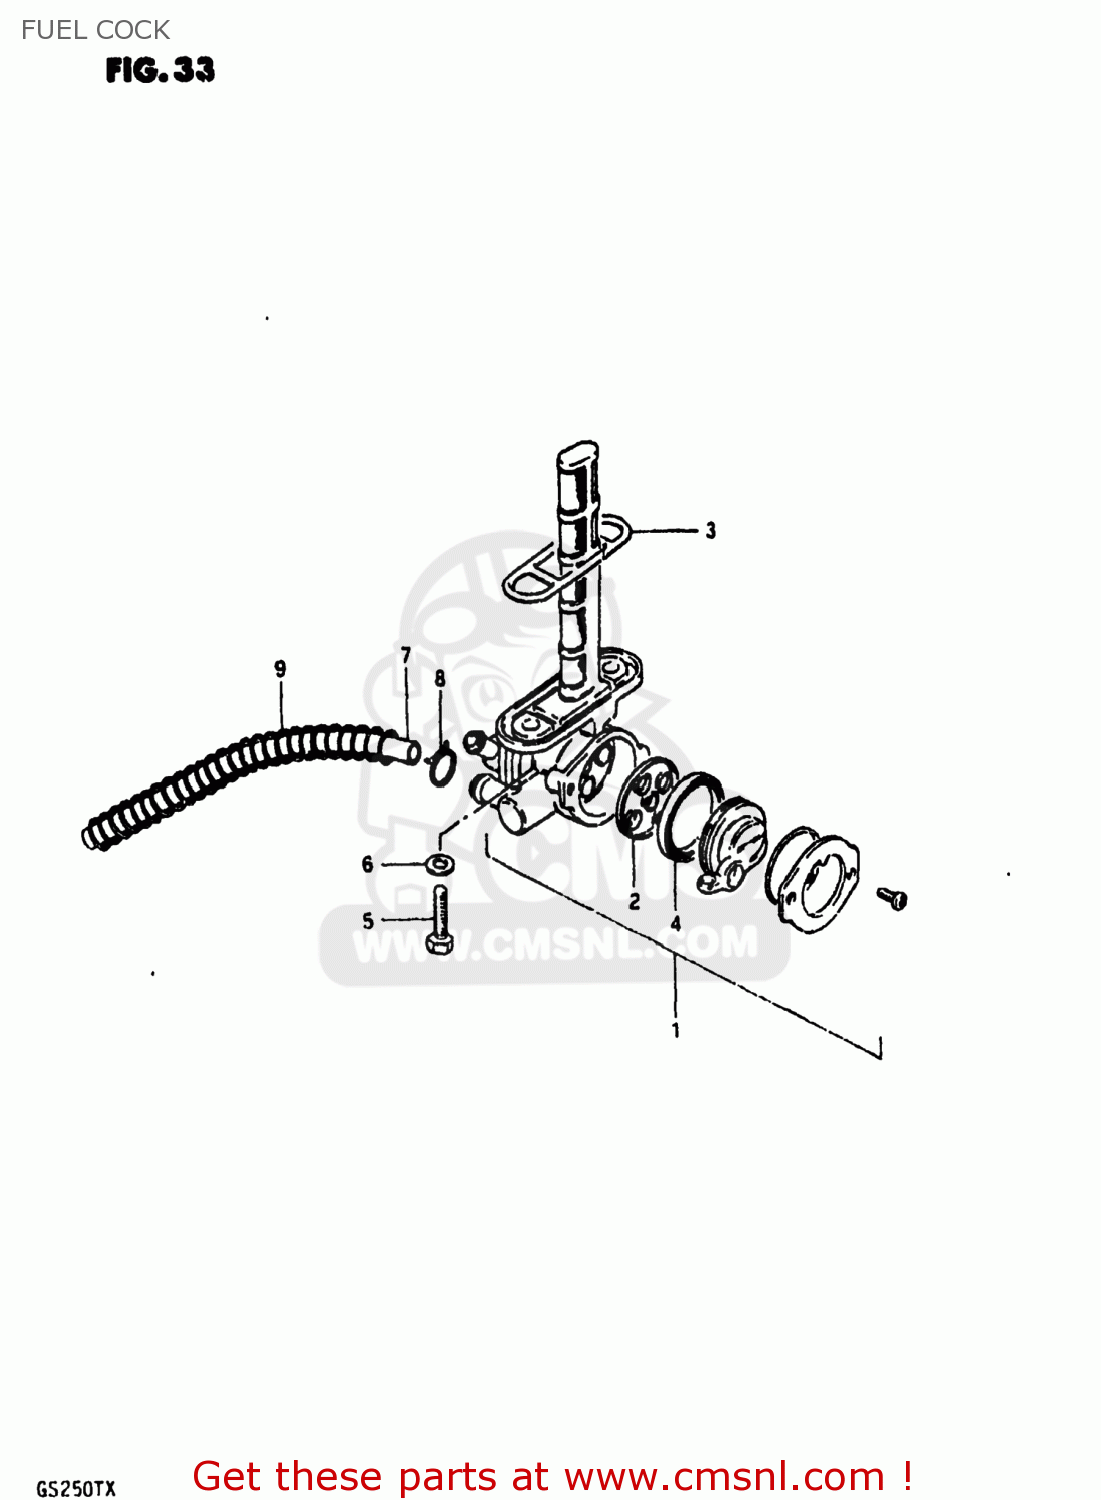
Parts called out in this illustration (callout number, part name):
1	COCK ASSY,FUEL
2	GASKET (NAS)
3	GASKET, FUEL COCK (NAS)
4	V SEAL,FUEL COCK
5	SCREW
6	GASKET
7	HOSE
8	CLIP
9	SPRING
